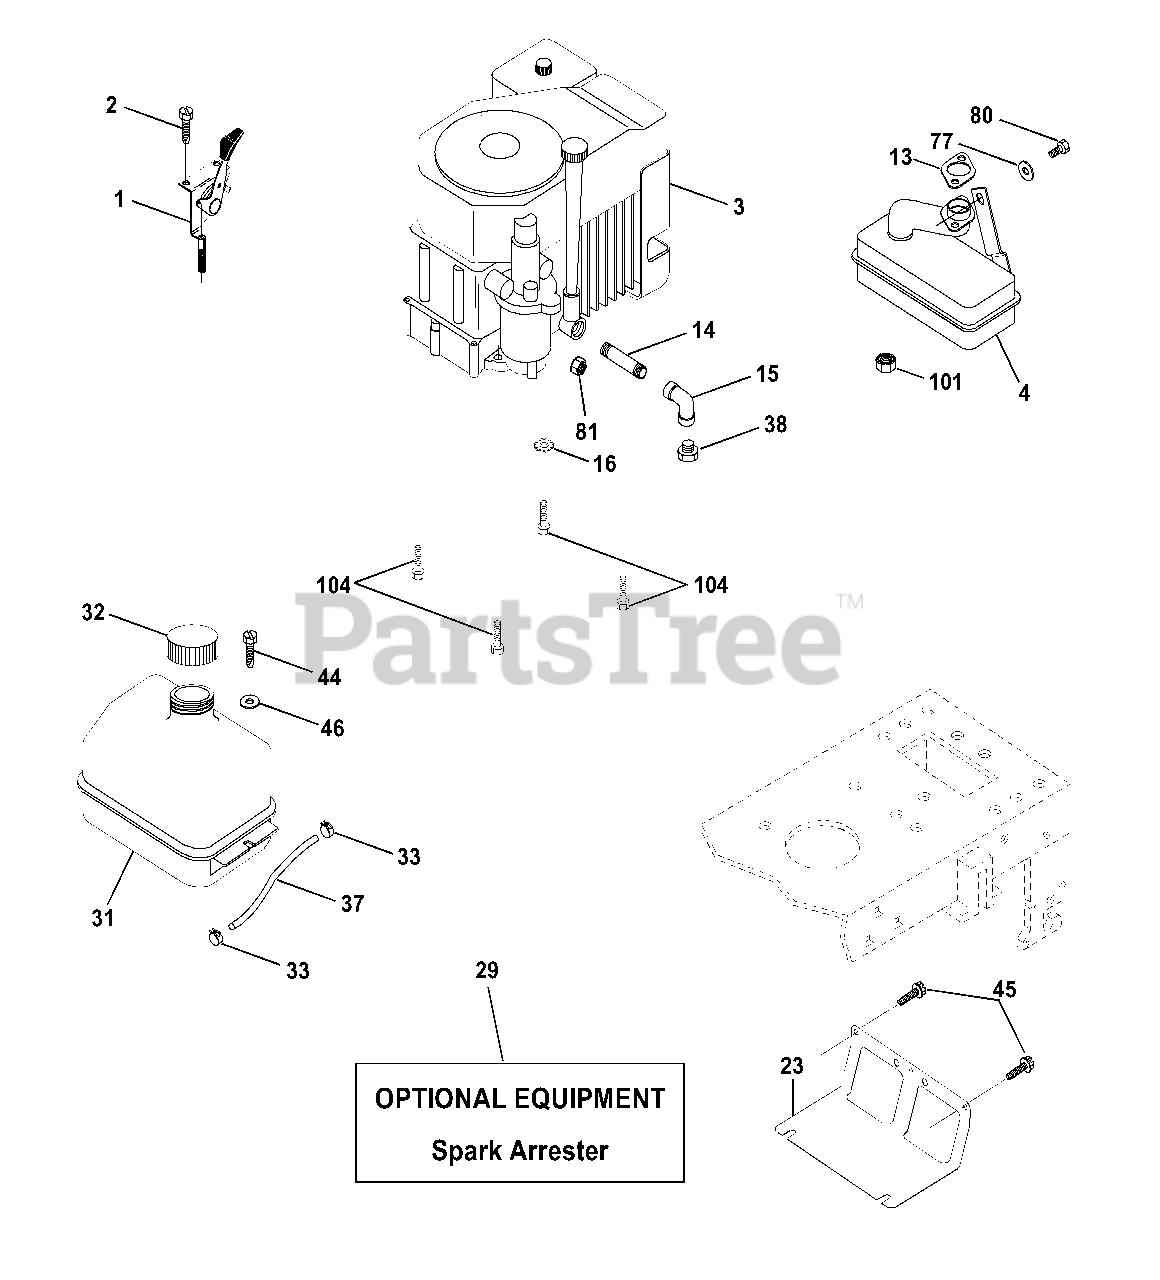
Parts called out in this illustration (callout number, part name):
1	Control, Throttle / Choke
2	Screw Hex Thd Cut 1/4-20 x 5/8
4	Muffler, Kohler
13	Kohler Gasket
14	Nipple, Pipe
15	Elbow, Standard 90°, 3/8-18 NPT
16	Washer, Lock Ext tooth 3/8
23	Shield, Browning/Debris Guard
29	Arrester, Spark
31	Tank, Fuel
32	Cap Gauge, Fuel
33	Clamp, Hose Blk
37	Line, Fuel
38	Plug, Oil Drain
44	Screw Hexwsh Thdrol 1/4-20 x 3/4
45	Screw 3/8-16 x 3/4
46	Washer 9/32 x 7/8 x 16 Ga
77	Washer 5/16 x 3/4 x 16 Ga.
80	Bolt Hex Hd 5/16-18 Unc x 1/2
81	Nut Flange 1/4-20 Starter Nut
101	Nut Flange M8 - 1.25
104	Screw 3/8-16 x 1-1/2
